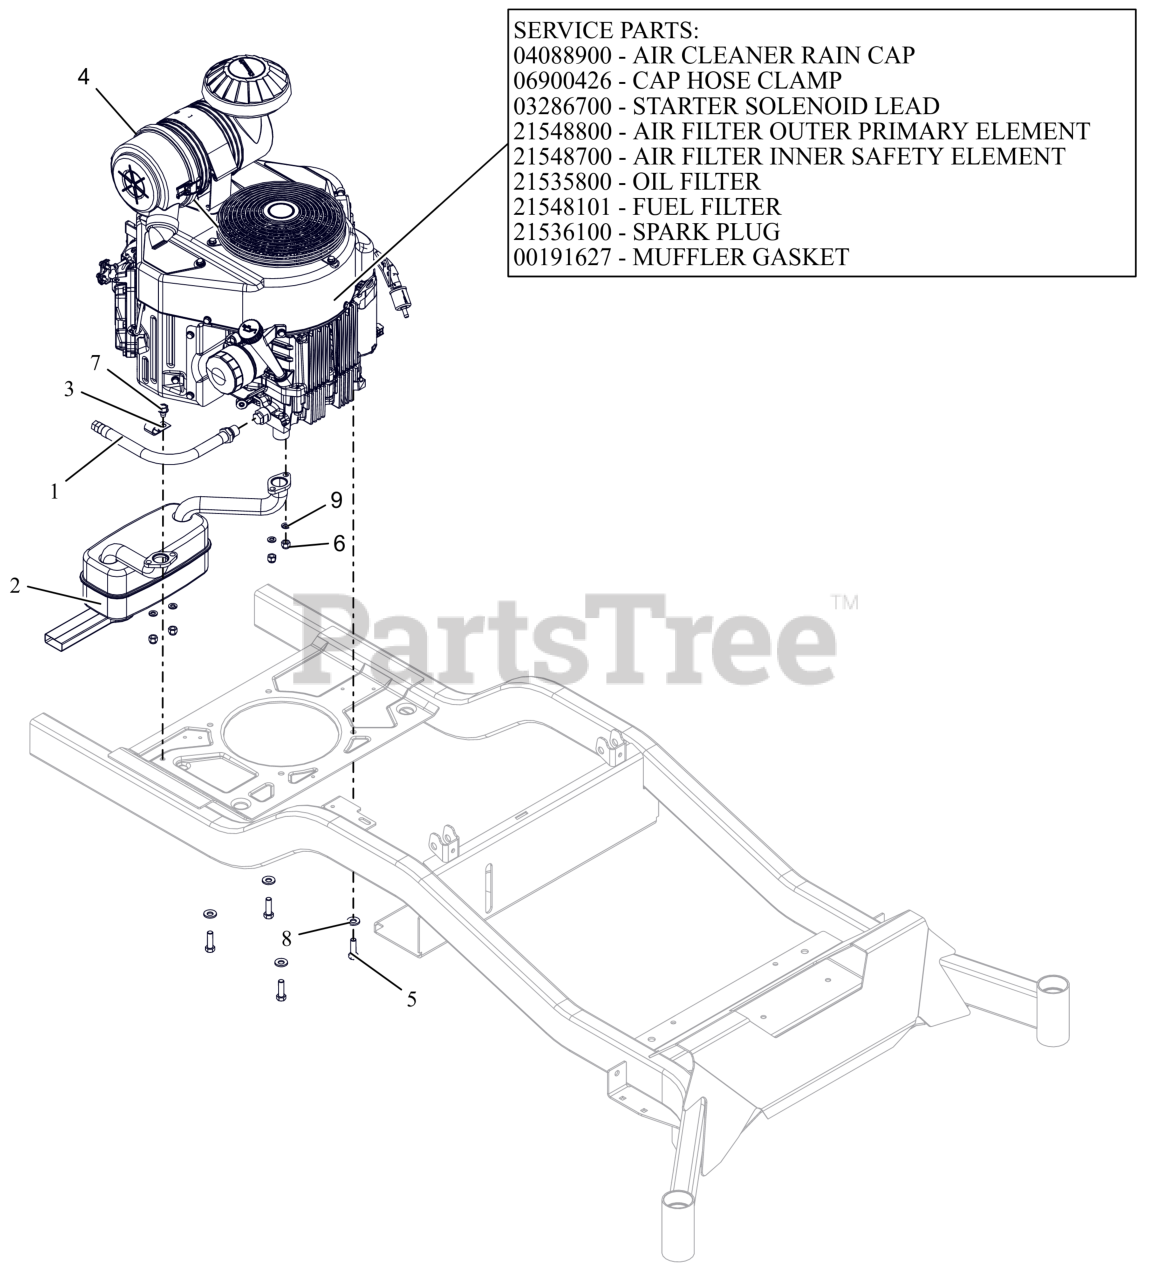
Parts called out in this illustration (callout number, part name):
1	HOSE, OIL DRAIN
2	MUFFLER, KAWASAKI
3	J-CLAMP
4	ENGINE, KAWASAKI - FX730
4	CAP, KAW 11065-7025
4	CLAMP, HOSE #36 SS 1.813-2.75
4	LEAD - STARTER SOLENOID
4	FILTER, OUTER
4	FILTER, INNER - KAW
4	FILTER,OIL - KAW
4	FUEL FILTER-KAWASAKI FR
4	PLUG, SPARK
4	GASKET, MUFFLER S/O
5	BLT, HEX .38-16X1.25 G5 ZCC NT
6	NUT, LK-CTR-JAM M8-1.25 GR8.8 ZC120
7	SCR,TAP .375-16X.50 HWH TR ZCC
8	WASHER, 3/8" SPRING DISC
9	WSHR,LK-REG .312X.078 ZCC
